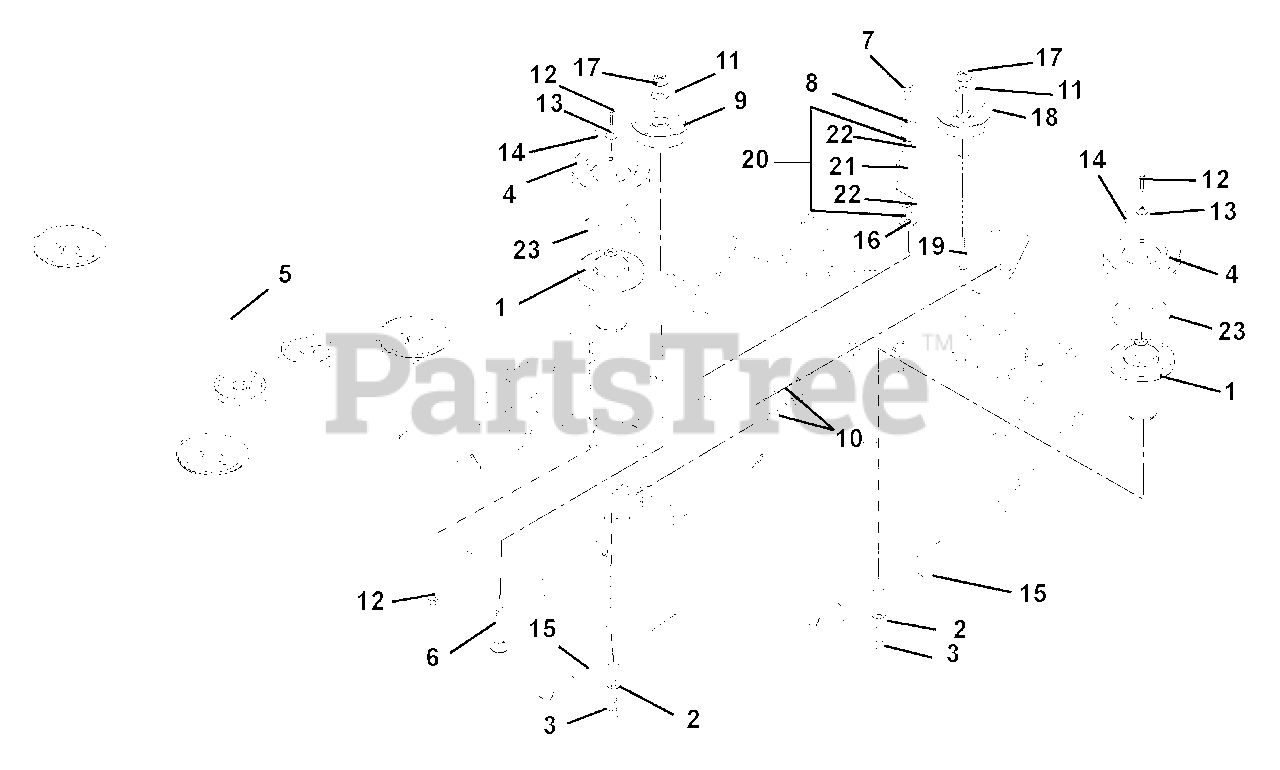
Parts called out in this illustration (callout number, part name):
1	ASM,MAINT FREE SPINDLE
2	WSHR-BLVL .669X1.535X.138
3	BLT-HEX .62-18X1.75 GR8 YWZC
4	SHEAVE, 5.00 SPINDLE (1.000ID)
5	V-BELT, HB-WRAPPED
6	@BLT-RDHDSQNK .38-16X2.75 G5YZ
7	@BLT-HEX .50-13X3.00 GR5 YWZC
8	BEARING, PEDESTAL
9	IDLER-FLAT 4.00X.38 (2.00 W)
10	SPRING, EXT0NSION DIA1.0X6.0LG
11	WSHR-FL-STL .375X1.125X.065YWZ
12	BLT-HEX .38-16X1.0 GR8 YZ EP30
13	WSHR,FLT STL.406X1.50X.245YWZC
14	KEY, SQ .25X.25X1.00 RC 40-50
15	BLD,MULCHING 50" MWR
16	@WSHR-FL-STL.563X1.38X.109YWZC
17	@NUT-LK-NYL-FLG .38-16 YWZC
18	IDLER, FLAT 4.00 X .38 (1.OOW)
19	@BLT-RDHDSQNK .38-16X2.00 G5YZ
20	ASSM, IDLER ARM PIVOT
21	WMT, IDLER PIVOT ARM
22	BRG, 1.00 X 1.12 X .75
23	SLINGER, DUST
